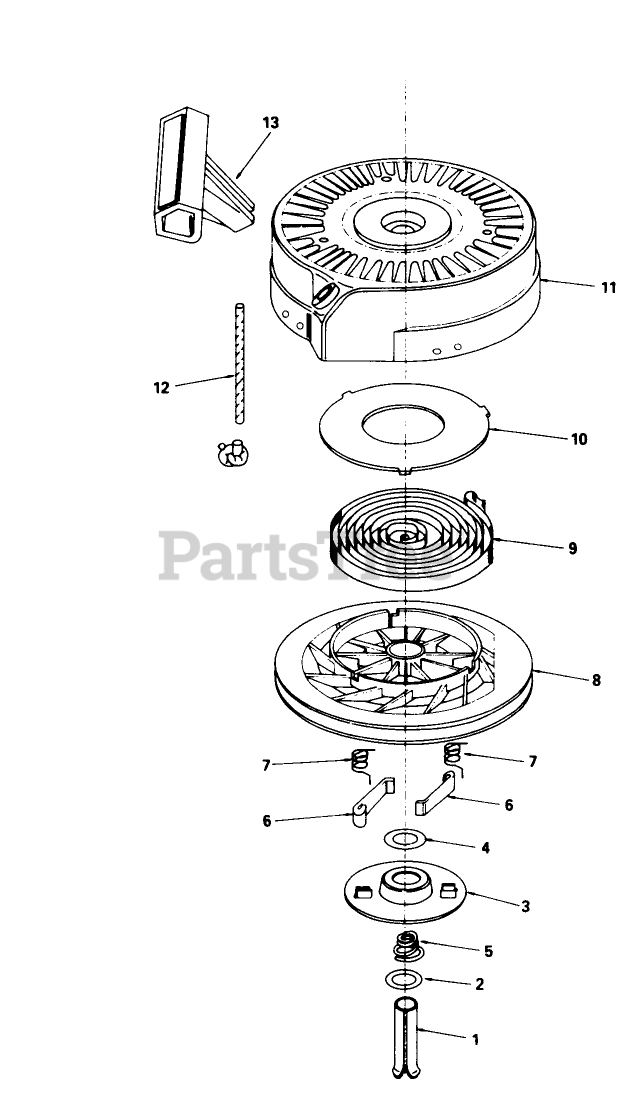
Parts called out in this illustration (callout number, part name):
1	Pin-Spring (Incl. Ref. #4)
3	Retainer
5	Brake Spring
6	Dog-Starter
7	Spring-Dog
8	Pulley
9	Rewind Spring
10	Cover-Spring
11	Housing-Starter
12	Rope-Starter (98 cut to length)
13	Handle-Starter
